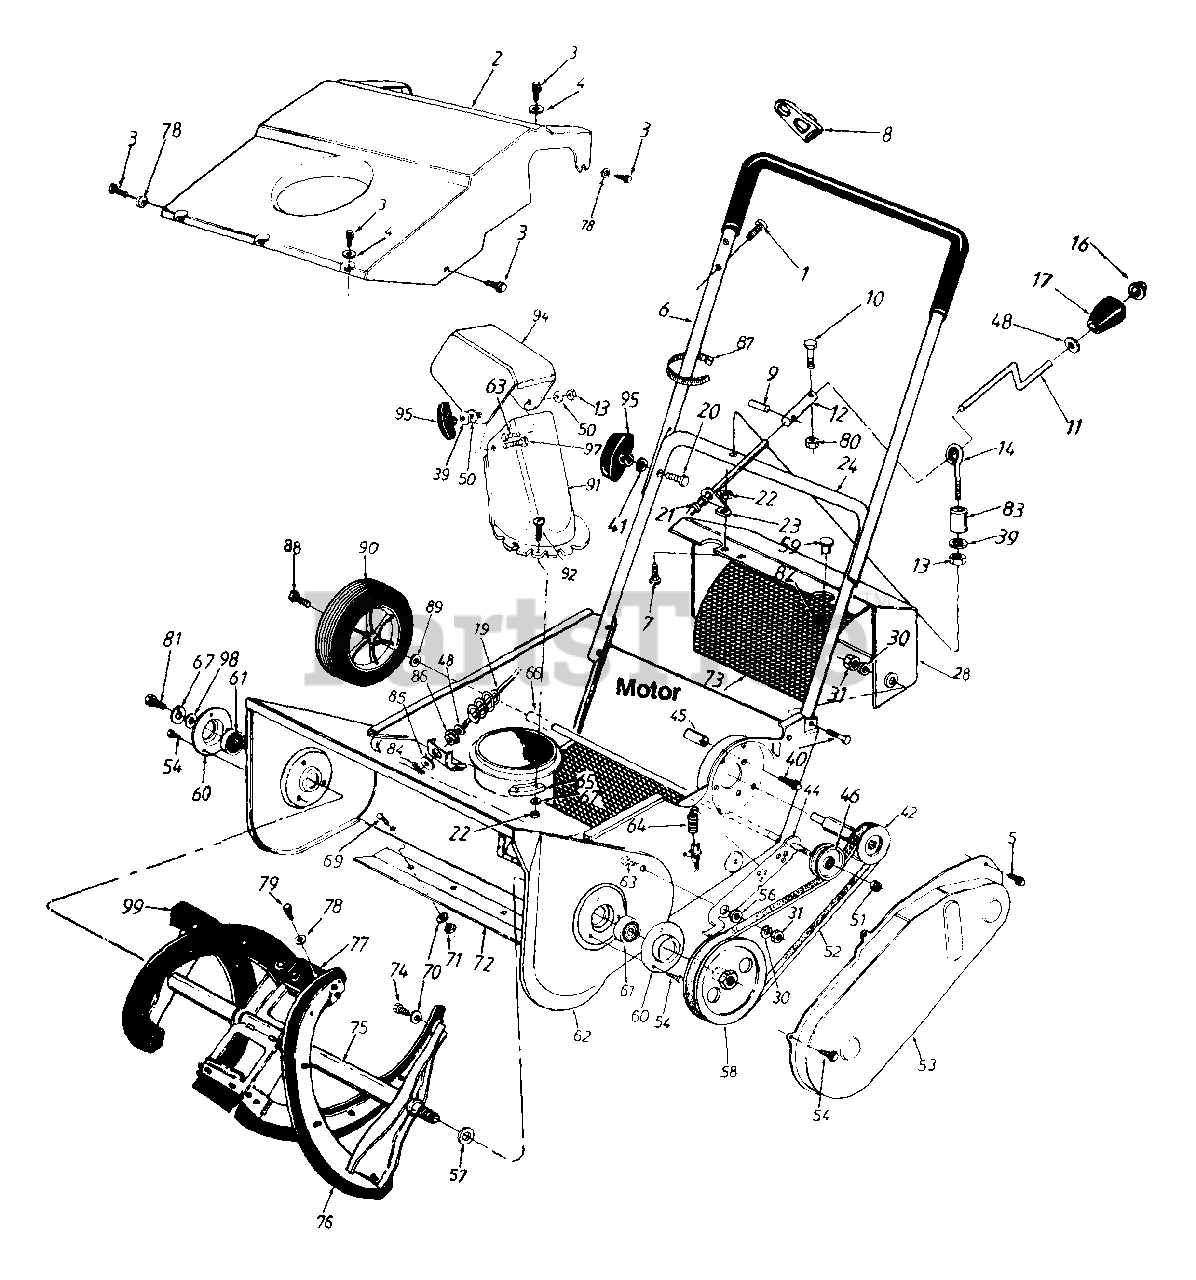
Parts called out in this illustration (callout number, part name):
1	Self-Tap Scr. #7 x 1" Lg.
2	Shroud - 21" Snow Thrower
3	Tap Scr. #10 x 3/8" Lg.
4	Washer - Spring
5	Tap Scr. 1/4 x 5/8" Lg.
6	Upper Handle (w/Vinyl)
7	Hex Bolt 1/4-20 x 1/2" Lg.
8	Cord Restraint
9	Roll Pin 1/8 x 5/8"
10	Mach. Scr. #6-32 x 7/8"
11	Chute Crank - Upper
12	Sleeve
13	Hex L-Nut 5/16-18 Thd.
14	Eyebolt
16	Retainer - Push Cap 3/8" Dia.
17	Knob - Chute Rod
20	Saddle Bolt 5/16-18 x 1-3/4" Lg.
21	Grommet
22	Hex L-Nut 1/4-20 Thd.
23	Chute Crank Brkt.
24	Lower Handle
28	Dash Panel (Electric)
30	L-Wash. 5/16" I.D.
31	Hex Nut 5/16-18 Thd.
39	Bell-Wash. .345" I.D. x .88" O.D.
40	Hex Bolt 5/16-18 x 1-1/2" Lg.
41	Curved Washer 5/16" I.D.
42	Pulley and Shaft Assembly
46	Idler - Flat 2-1/8" O.D.
48	Washer 3/8" I.D. x 5/8" O.D.
50	Washer 5/16" I.D. x 1-1/4" O.D.
51	Hex L-Nut 3/8-24 Thd.
52	"V"-Belt
54	Tap Scr. 1/4 x 3/8" (Special Tap)
56	Spacer - Shoulder
57	Fl-Wash. .51" I.D.
58	"V"-Pulley 1/2-20 L.H. Thd.
59	Rivet
62	Housing Assembly
63	Truss Mach. Scr. 5/16-18 x 3/4" Lg.
64	Spring - Idler
65	Keeper - Chute Flange
66	Axle - Wheel
67	L-Wash. 1/4" I.D.
69	Carriage Bolt 1/4-20 x .62" Lg.
70	Washer 1/4"
71	Hex Jam Nut 1/4-20 Thd.
72	Scraper Bar
73	Baffle
74	Tap Scr. 1/4 x 5/8" Lg.
76	Rubber Spiral - L.H.
77	Rubber Paddle
78	Washer 3/16" I.D. x 7/8" O.D.
79	Tap Scr. #10 x 5/8" Lg.
80	Hex L-Nut #6-32 Thd.
81	Tap Scr. 1/4 x 5/8" Lg.
82	Fl-Wash..203" I.D. x .812"
83	Spacer - Eyebolt
84	Cotter Pin 3/32" x 3/4"
85	Washer .406" I.D. x 1-1/4" O.D.
86	Hex Bushing
87	Plastic Tie
88	Retainer - Push Cap 1/2" Dia.
89	Washer 1/2" I.D.
90	Wheel - 7"
91	Lower Chute
92	Truss Mach. Scr. 1/4-20 x 1" Lg.
94	Upper Chute
95	Hand Knob
97	Carriage Bolt 5/16-18 x 1" Lg.
98	Fl-Wash. .25" I.D.
99	Rubber Spiral - R.H.
